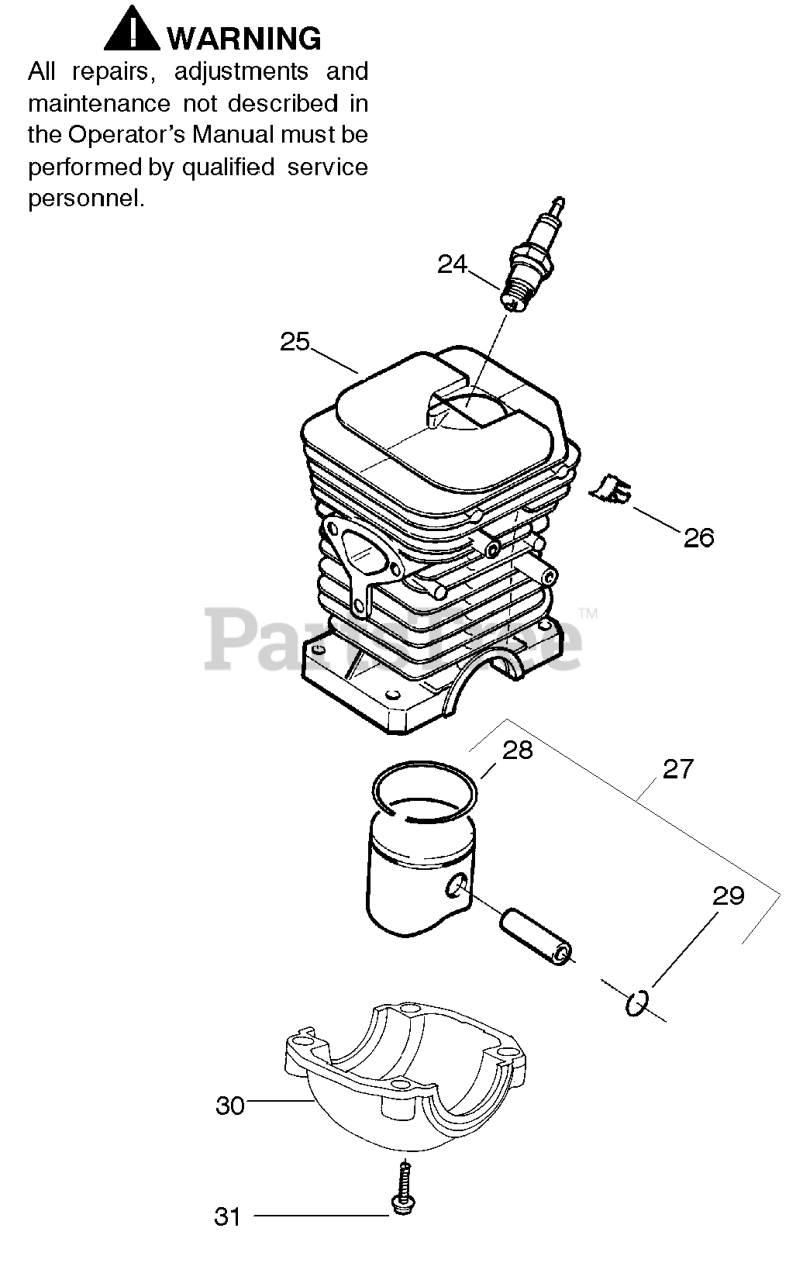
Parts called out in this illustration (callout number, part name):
24	Spark Plug
25	CYLINDER ASSY/136
26	CLIP - HIGH TENSION LE
27	PISTON KIT/136
28	PISTON RING 36
29	C-CLIP,PSTN PIN 36/41
30	CAP-CRANKSHAFT
31	SCREW-M5-0.8 X 25MM(TAP)
